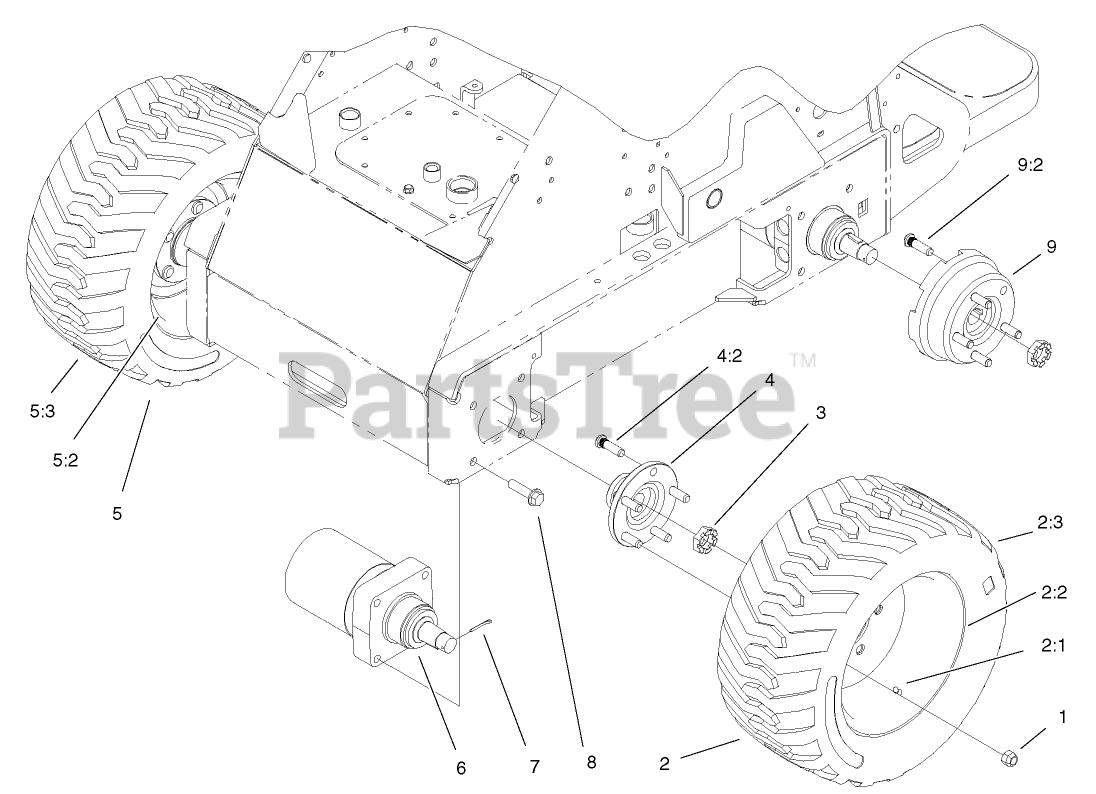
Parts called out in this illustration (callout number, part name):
1	NUT-LUG
2	LH WHEEL AND TIRE ASM
2:1	STEM-VALVE
2:2	WHEEL
4	HUB ASM
4:2	STUD-TYPE, DRIVE
5	RH WHEEL AND TIRE ASM
5:1	STEM-VALVE
5:2	WHEEL
6	HYD MOTOR ASM
7	PIN-COTTER
8	SCREW-HHF
9	WHEEL HUB ASM
9:2	STUD-TYPE, DRIVE
